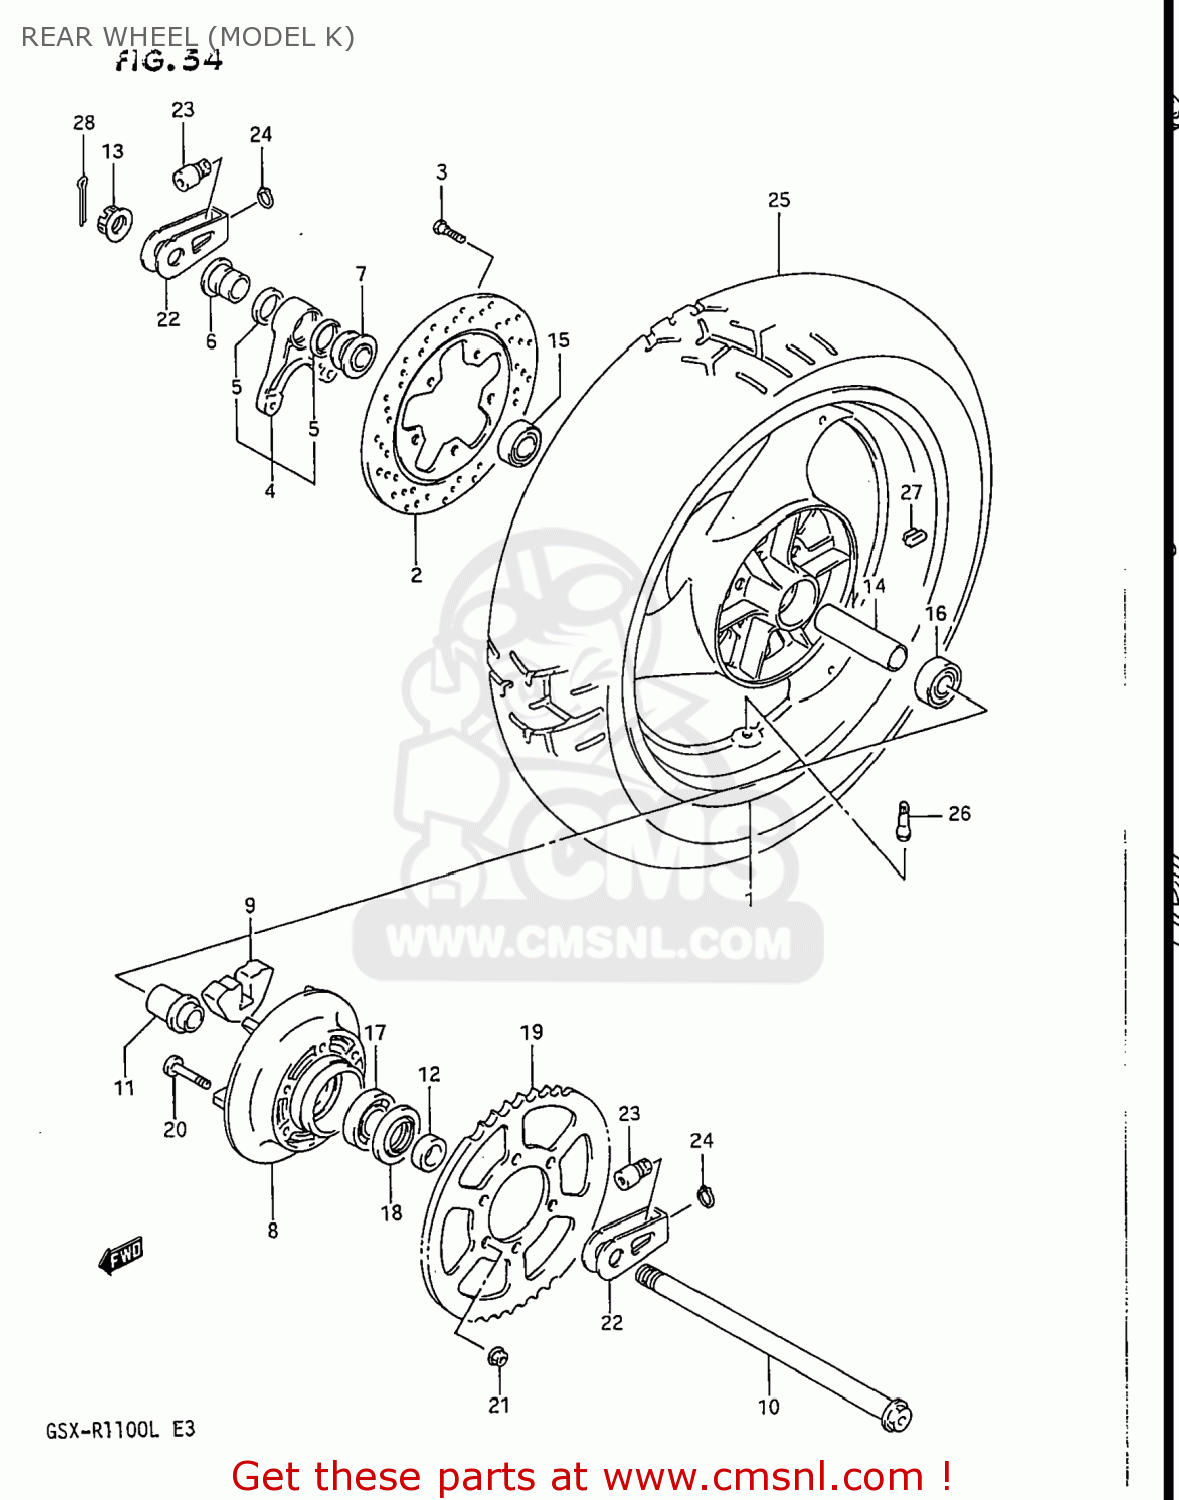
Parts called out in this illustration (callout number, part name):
1	WHEEL,REAR
2	DISC,RR BRAKE
3	BOLT
4	BRACKET,RR CALIPER
5	SEAL,OIL(28X35X5)
6	SPACER,RR CALIPER BRACKET
7	SPACER,RR AXLE,R
8	DRUM,RR SPROCKET MOUNTING
9	ABSORBER,RR HUB SHOCK
10	AXLE,RR
11	RETAINER,RR HUB BEARING
12	SPACER,RR AXLE,L
13	NUT
14	SPACER,RR WHEEL HUB BEARING
15	BEARING(20X47X14)
16	BEARING(20X47X14)
17	BEARING(25X62X17)
18	SEAL,OIL(35X62X8)
19	SPROCKET,REAR
20	BOLT
21	NUT
22	ADJUSTER,CHAIN
23	ADJUSTER,CHAIN
24	CIRCLIP
25	TIRE,REAR 160/60 ZR17
26	VALVE ASSY,WHEEL RIM(TR412)
27	BALANCER,WHEEL
28	PIN, COTTER
